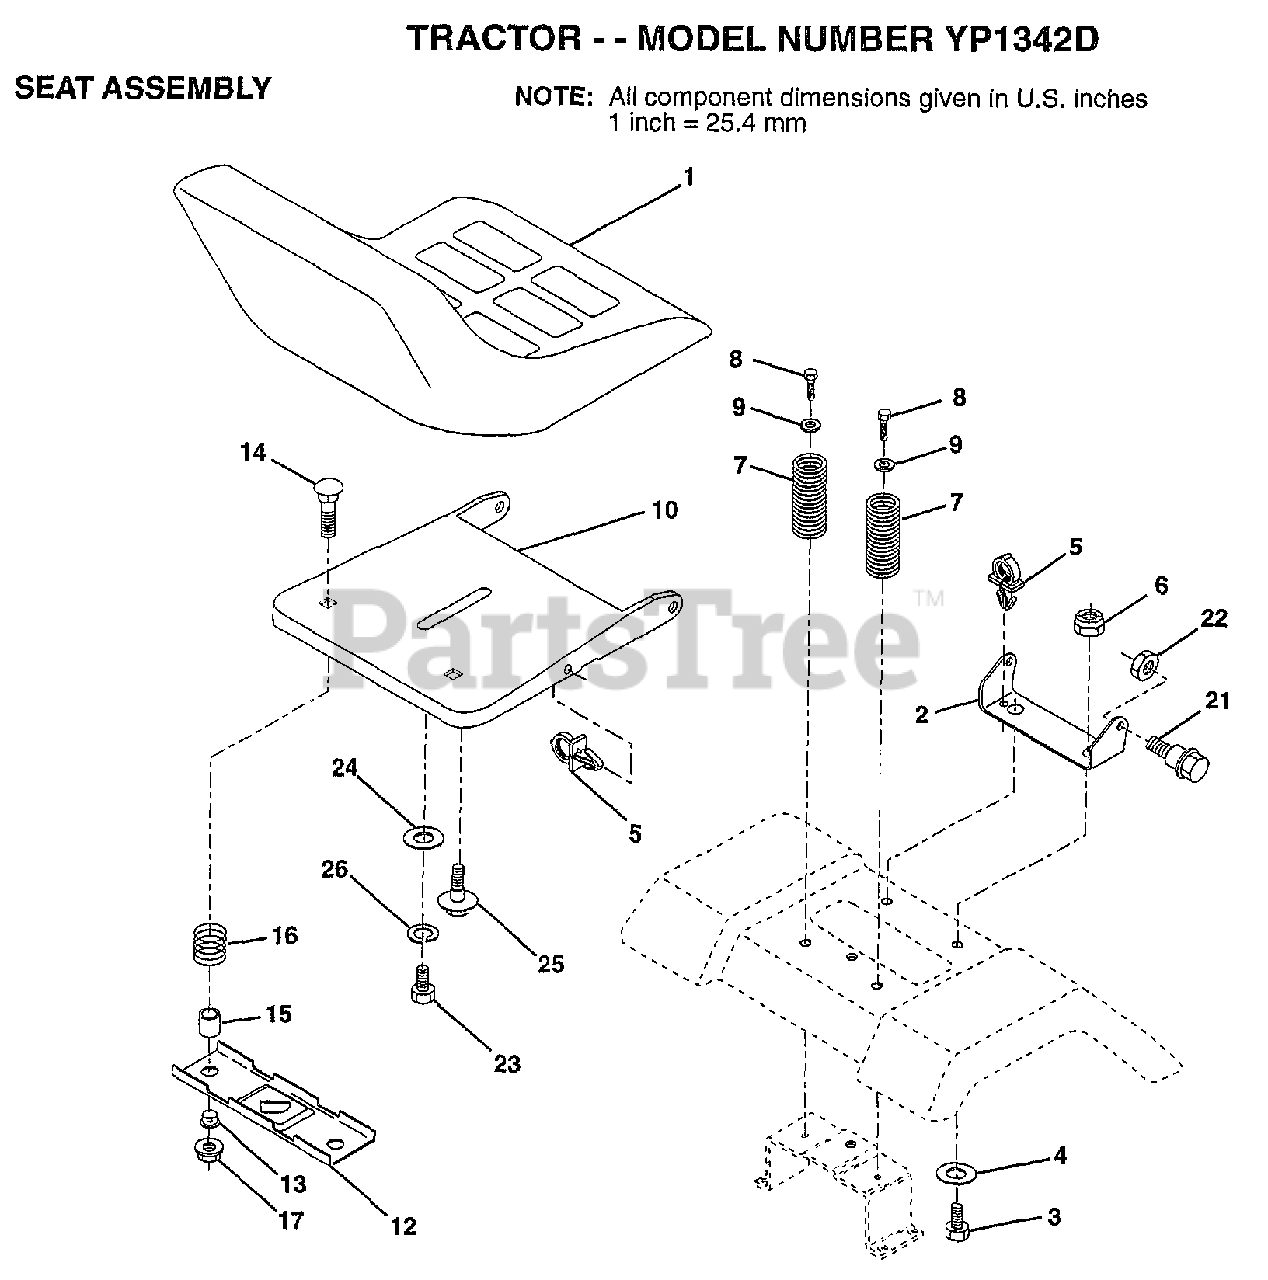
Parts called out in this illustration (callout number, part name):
1	SEAT
2	BRACKET PVT SEAT
3	BOLT
4	WASHER PM
5	CLIP.PUSH-IN.HING
6	NUT
7	SPRING COMPRESSIO
8	SCREW GTV
9	WASHER
10	PAN-SEAT
12	BRKT SWITCH
13	BUSHING
14	BOLT-RD HD SQ NK
15	SPLIT SPACER
21	"BOLT,SHOULDER"
22	NUT
23	BOLT
24	WASHER
25	"BOLT,SHOULDER"
26	LOCKWASHER
